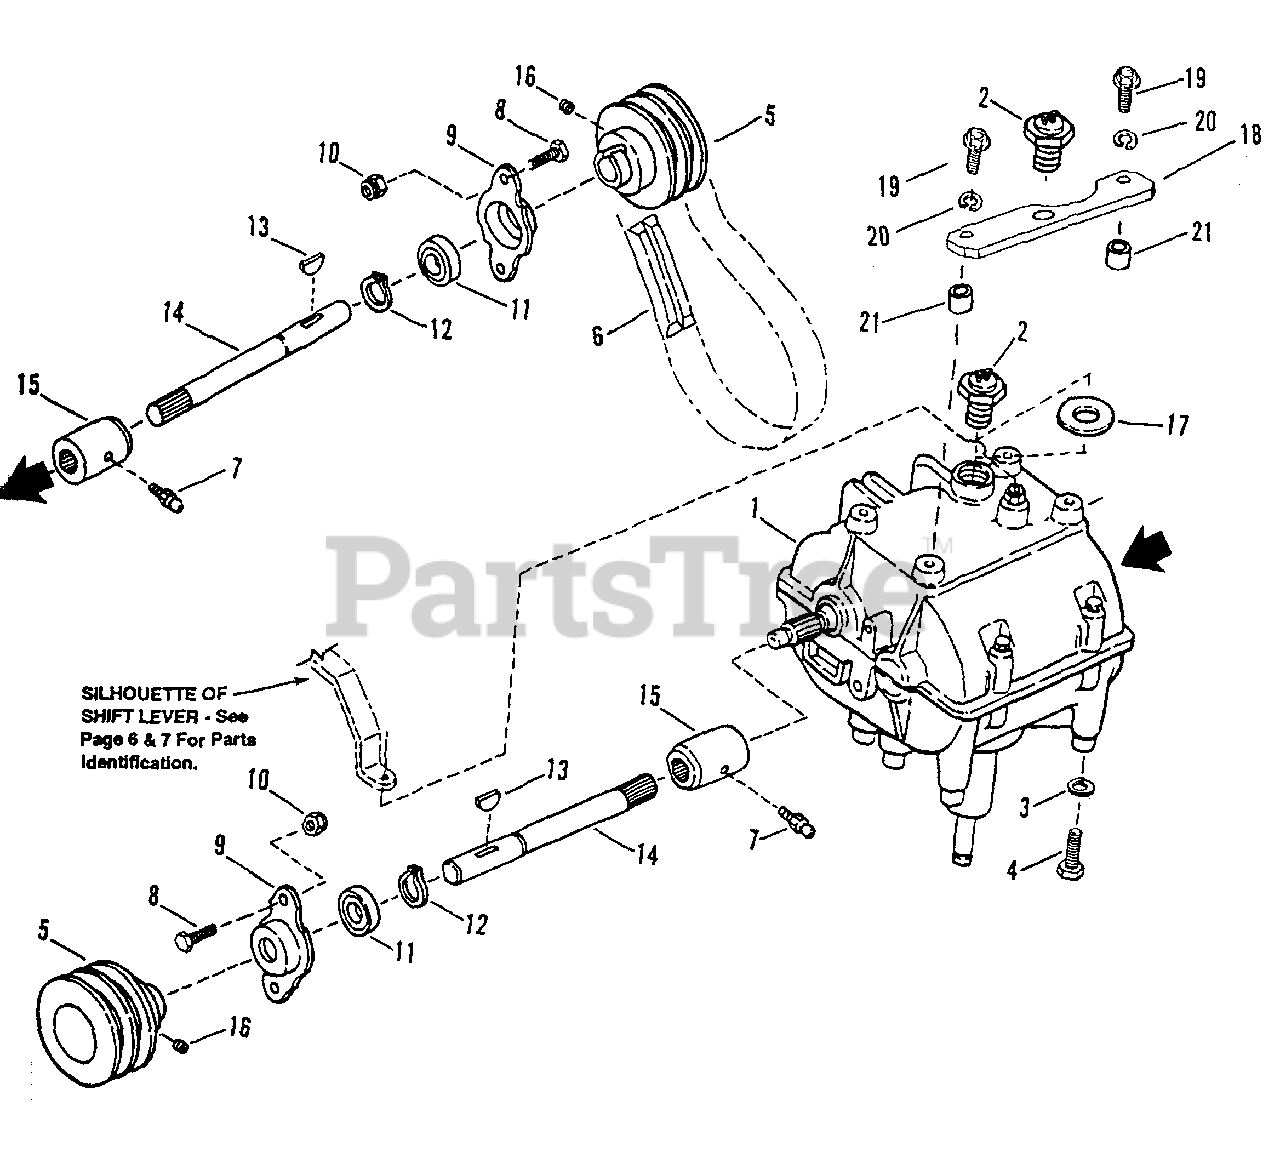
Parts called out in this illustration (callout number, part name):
1	TRANSMISSION (5 Speed)
2	SWITCH, Transmission
3	WASHER, 5/16 Split Lock
4	BOLT, 5/16-18 x 3/4" Hex Head Cap
5	PULLEY, Output
6	BELT, Traction (Dual Belt)
7	FITTING, Lube
8	SCREW, 1/4-20 x 3/4" Hex Head Cap, Grade 5
9	FLANGE, Output
10	NUT, 1/4-20 Nyloc
11	BEARING, Output
12	RING, Retaining
13	KEY, 09 Woodruff
14	SHAFT, Output
15	COUPLER
16	SCREW, 5/16-18 x 3/8" Knurled Cup Point Set
17	WASHER, Fiber
18	PLATE, Reverse Interlock
19	SCREW, 5/16-18 x 1-1/4 Hex Washer Head Self Tap
20	WASHER, 3/8" SPLIT LOCK
21	BUSHING
